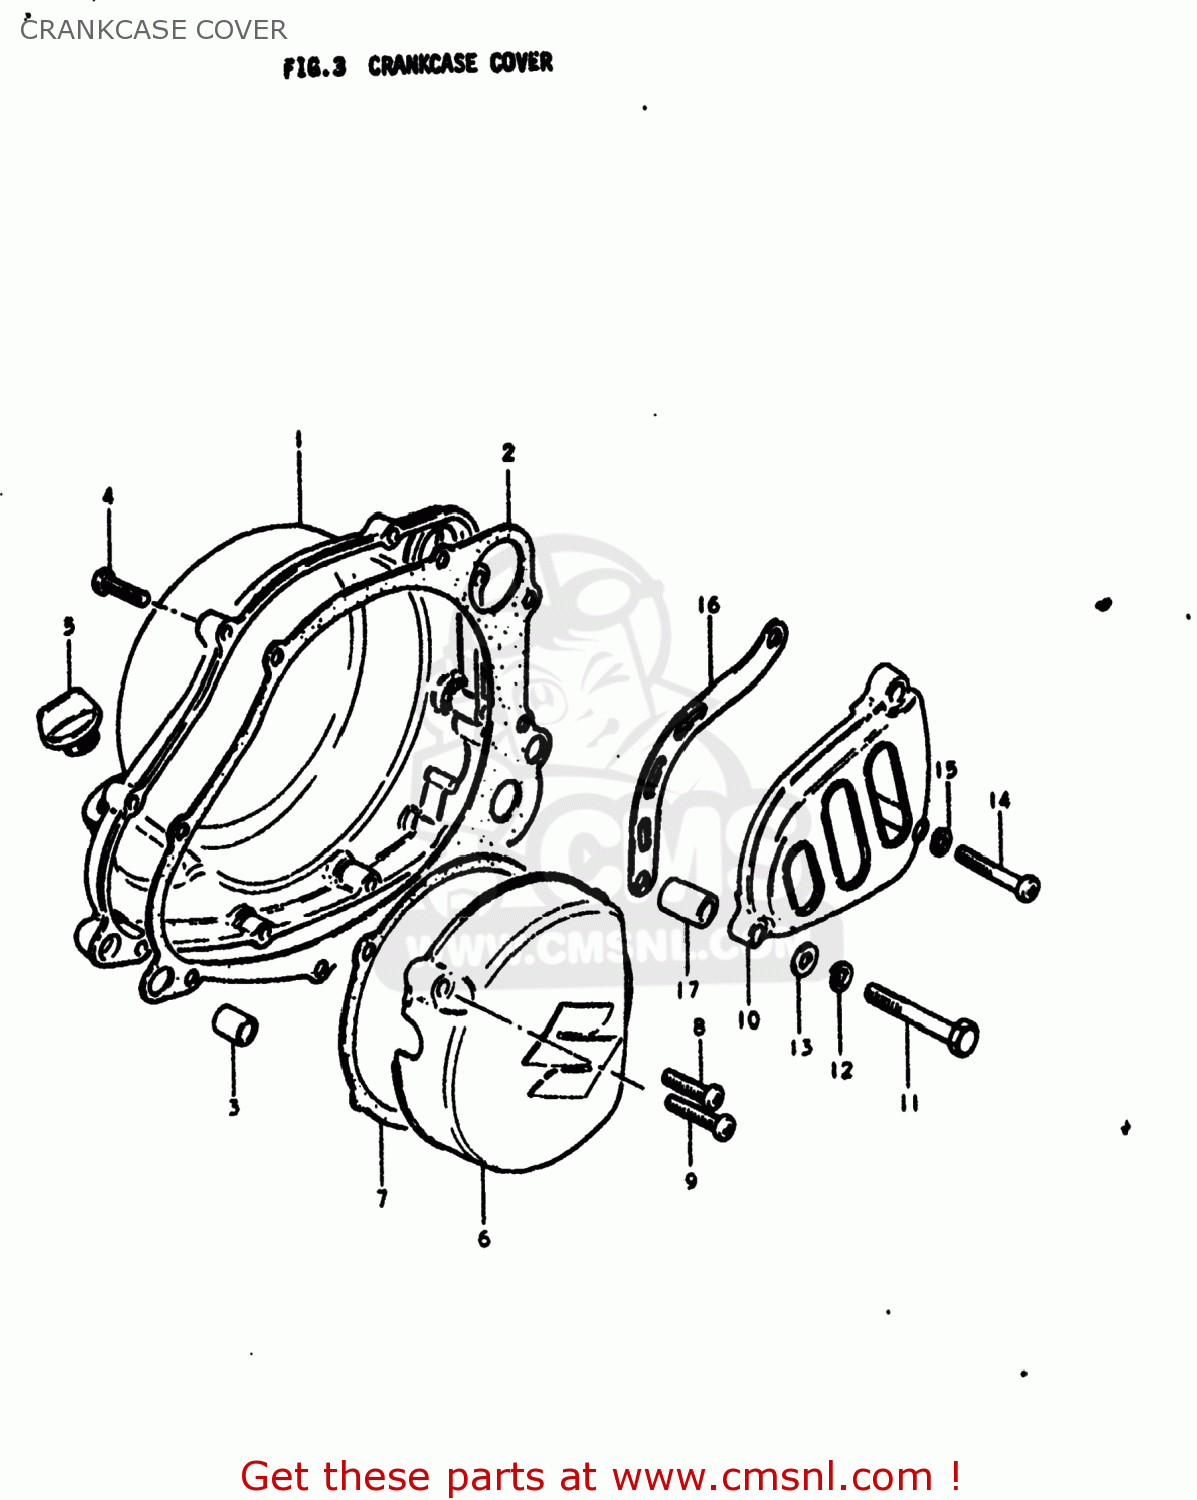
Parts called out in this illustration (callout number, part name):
1	COVER,CLUTCH
2	GASKET,CLUTCH COVER (MCA)
3	PIN
4	SCREW
5	PLUG,OIL FILTER
6	COVER
7	GASKET,MAGNETO COVER (MCA)
8	SCREW
9	SCREW 6X30
10	COVER,SPROCKET
11	BOLT 8X55
12	LOCK WASHER
13	WASHER
14	SCREW
15	LOCK WASHER
16	PLATE,FR CHAIN GUIDE
17	SPACER(8.6X16X24)
